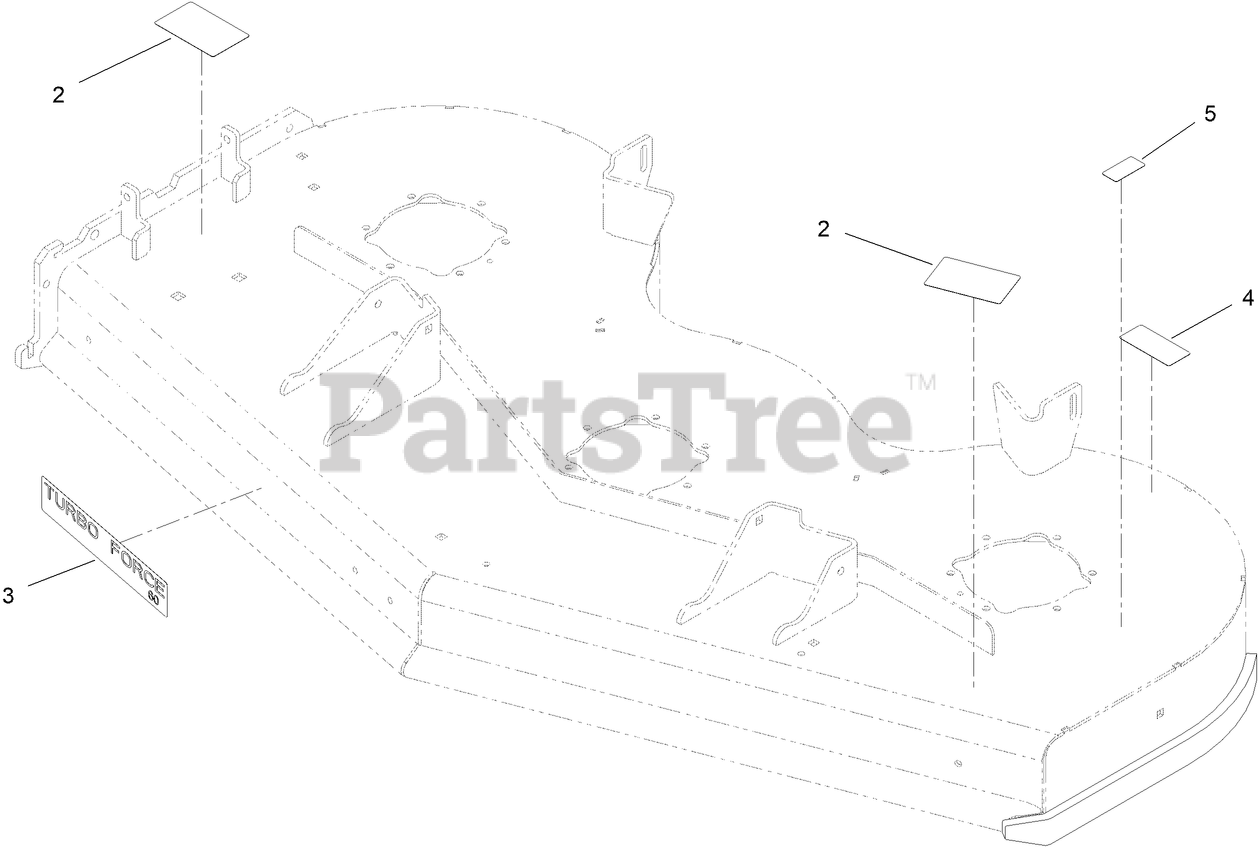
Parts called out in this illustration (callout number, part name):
2	DECAL-DANGER, CE
4	DECAL-DANGER
5	DECAL-NO SPRAY
